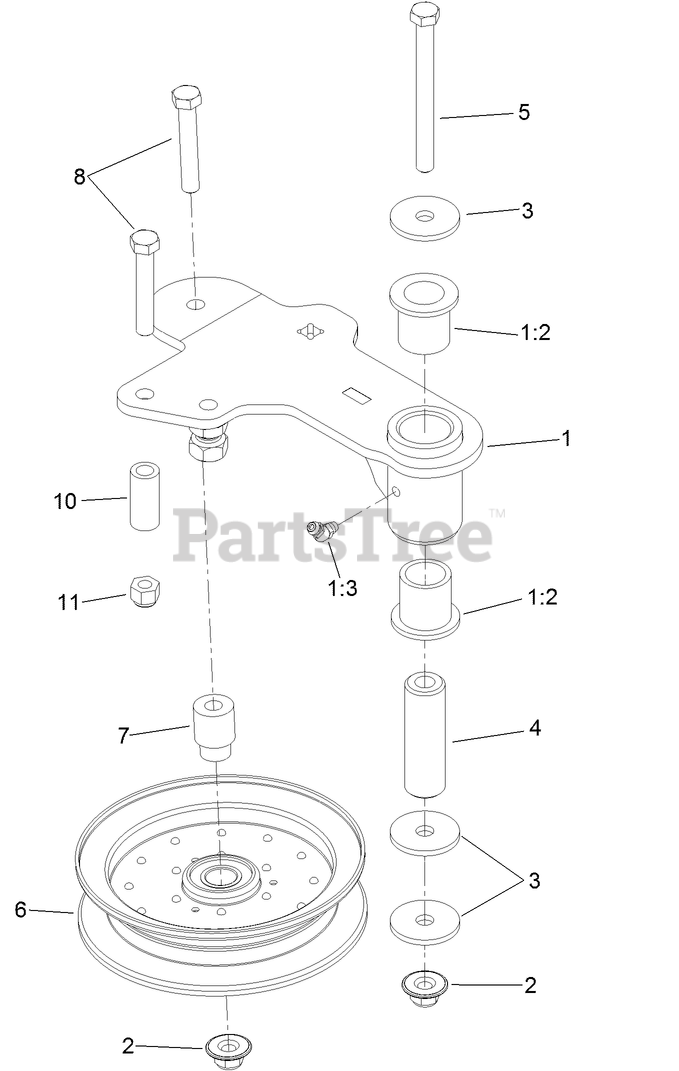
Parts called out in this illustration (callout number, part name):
1	IDLER ARM ASM
1:2	BEARING-FLANGED
1:3	FITTING-GREASE
2	NUT-FLANGE, NI
3	WASHER
4	SPACER-PLAIN
5	SCREW-HH
6	IDLER-PULLEY, FLANGED
7	MOUNT-PULLEY
8	SCREW-HH
10	SPACER
11	NUT-LOCK, NI
